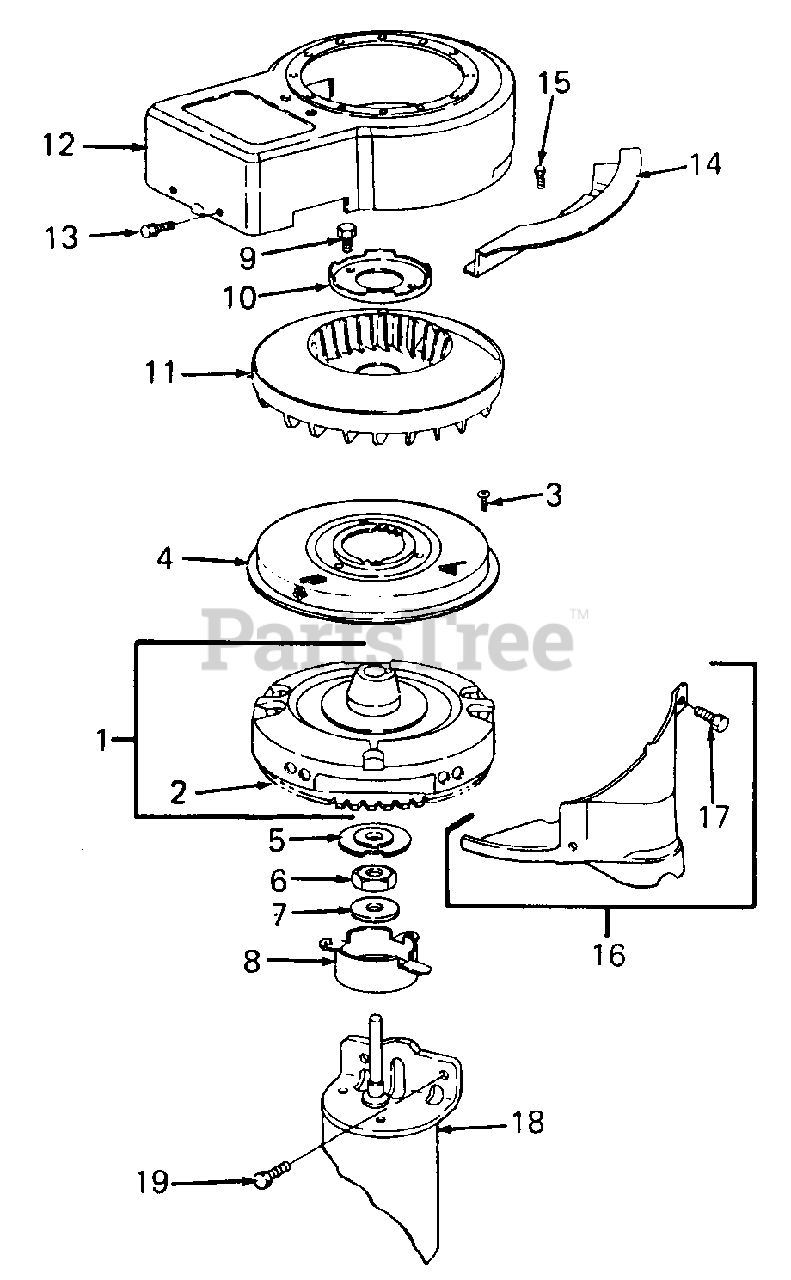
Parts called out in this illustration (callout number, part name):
1	Flywheel & Ring Gear Assy - Magneto
2	Gear, Ring
3	Screw, Sems
4	Screen, Flush Rotating
6	Nut, Hex
7	Washer, Spring
8	Cup, Screen Mounting
9	Screw, Sems
10	Retainer, Fan
11	Fan, Flywheel
12	Housing, Blower
13	Screw, Hex Washer Head
14	Guard, Flywheel
15	Screw, Hex Head
16	Cover, Starter
17	Screw, Sems
18	Motor, Starting
19	Screw, Sems
